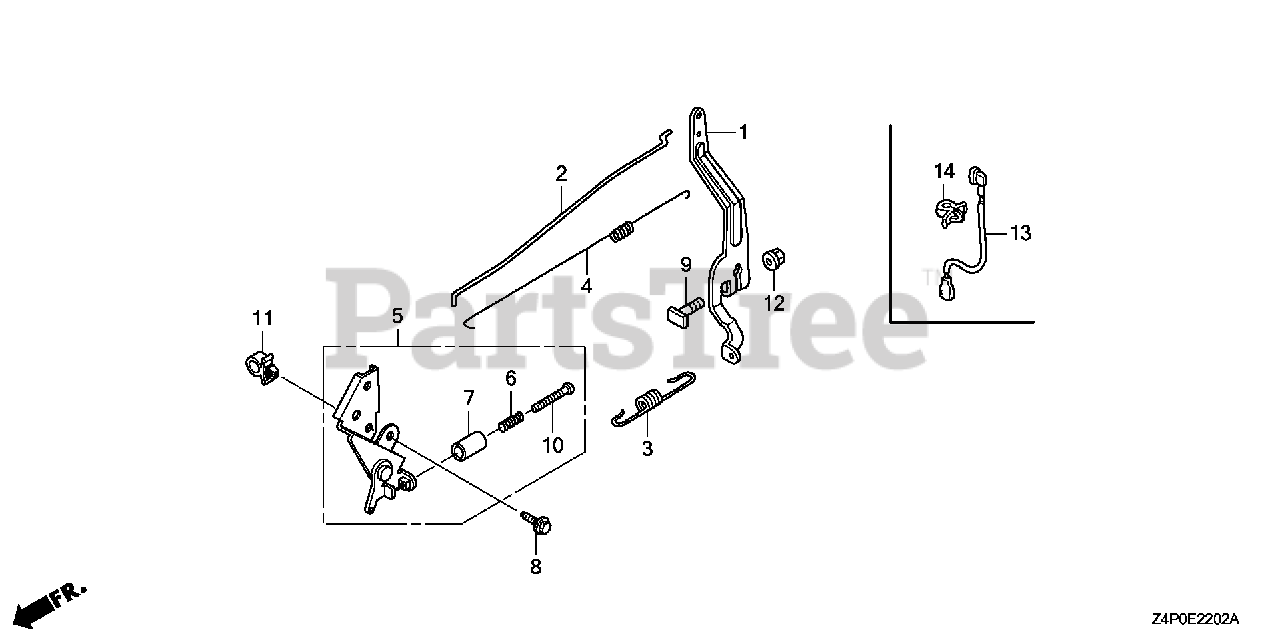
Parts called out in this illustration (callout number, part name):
1	ARM, GOVERNOR
2	ROD, GOVERNOR
3	SPRING, GOVERNOR (STD)
4	SPRING, THROTTLE RETURN
6	SPRING, CONTROL ADJUSTING Use from Engine SN 2327377.
7	COLLAR, STOPPER
8	BOLT, FLANGE (6X12) (CT200)
9	BOLT, GOVERNOR ARM
10	SCREW, RECESSED (5X35)
11	CLIP, HARNESS
12	NUT, FLANGE (6MM)
13	WIRE, STOP SWITCH
14	CLAMP, HARNESS
